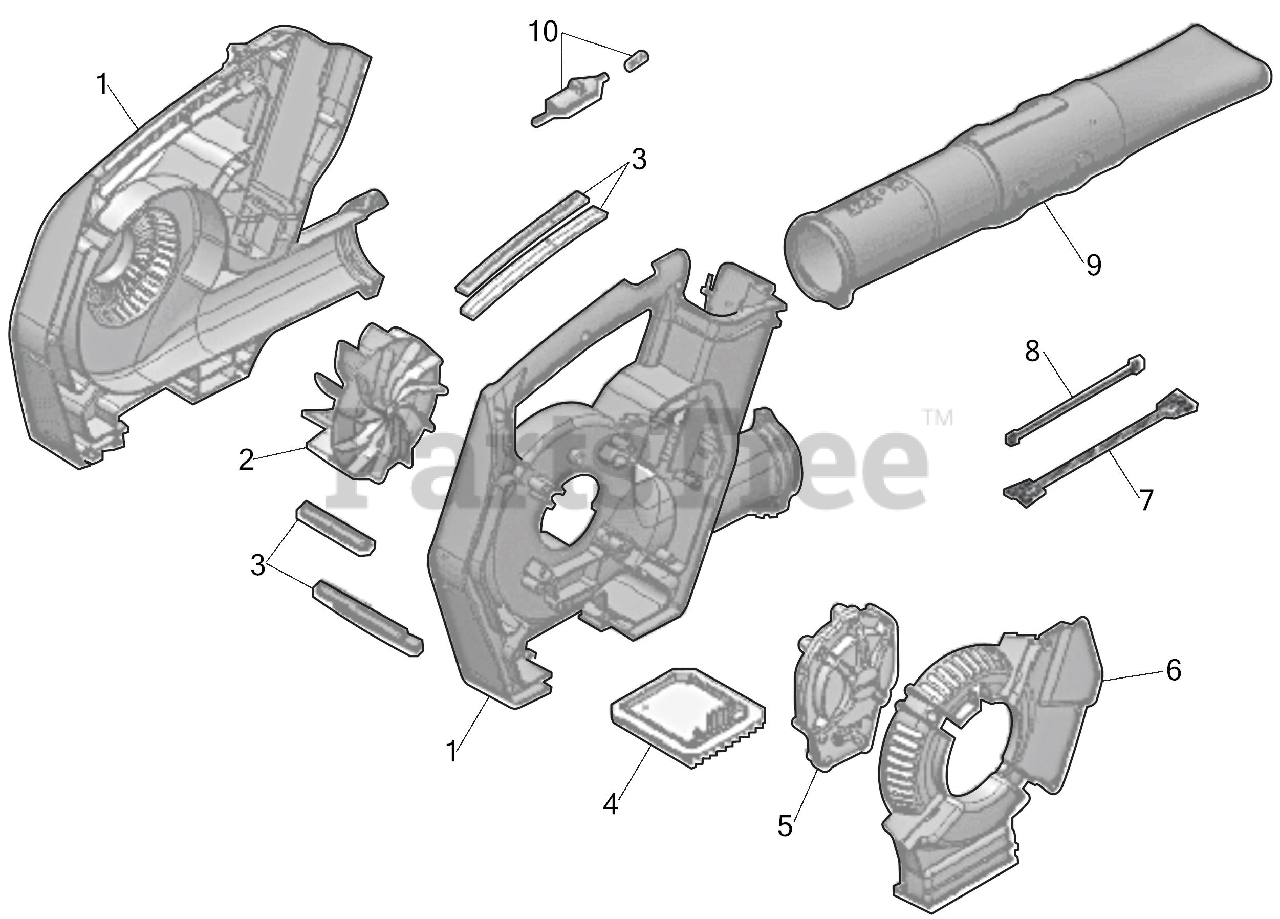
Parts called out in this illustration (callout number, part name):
1	HOUSING ASSEMBLY BLO E420 CORE
2	IMPELLER ASSEMBLY CPL420 CORE
3	GRIP ASSEMBLY BLO E420 CORE
4	CONTROL ASSEMBLY BLO E420 CORE
5	MOTOR ASSEMBLY BLO E420
6	ENGINE COVER E420 CORE
7	HARNESS:PHASE WIREE420 CORE
8	HARNESS:HALL WIRE E420 CORE
9	TUBE ASSEMBLY CPL420 CORE
10	SWITCH BLO E420 CORE
